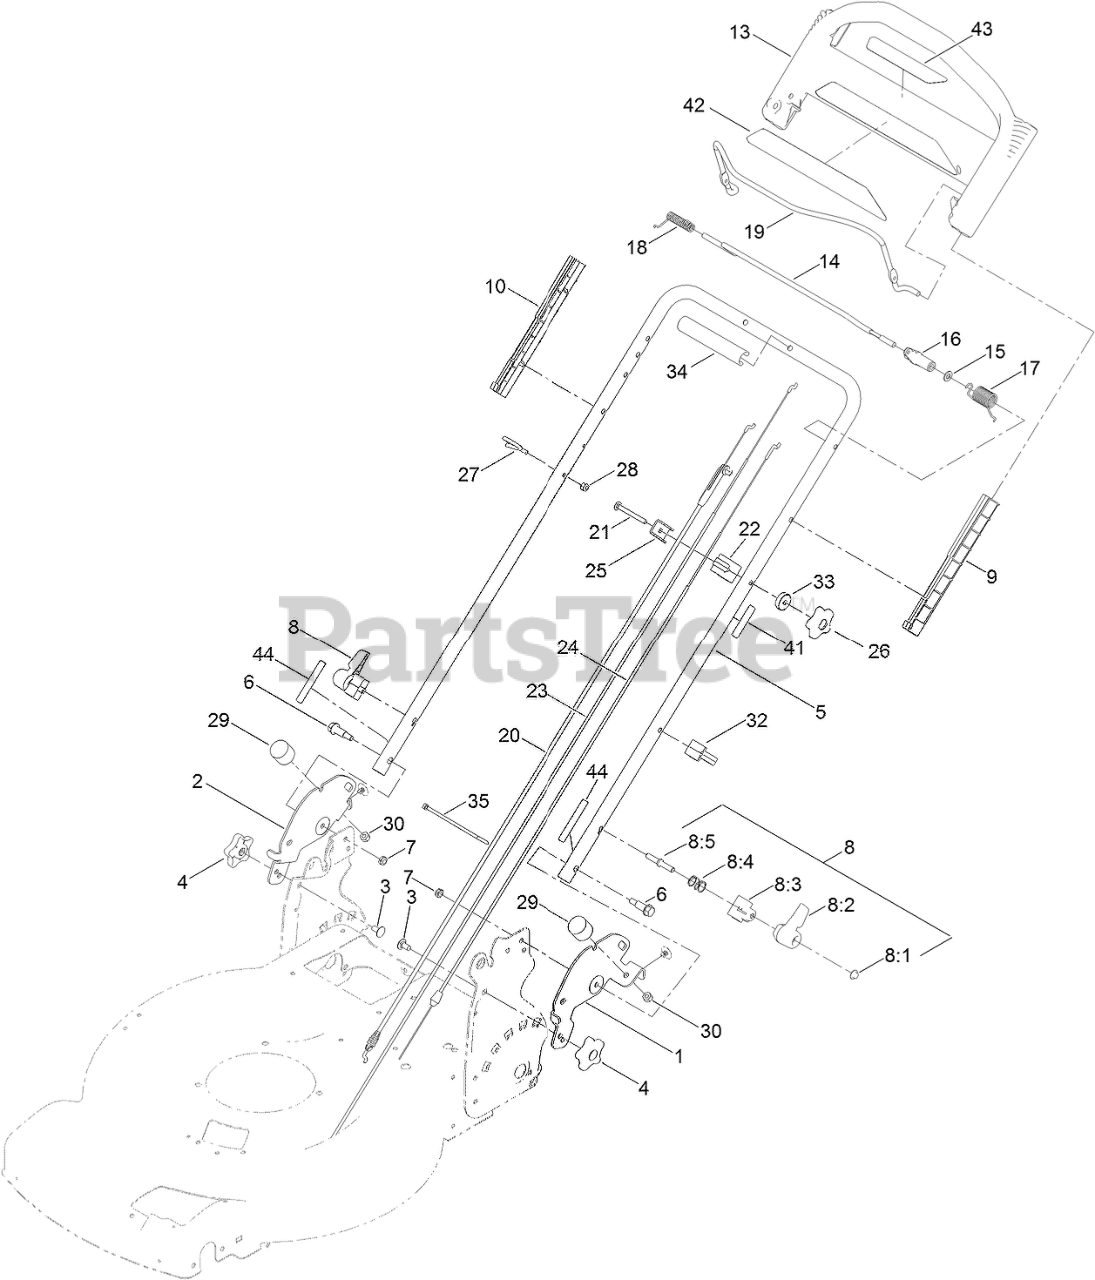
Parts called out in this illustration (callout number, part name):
1	BRKT-FLOAT, LH
2	BRKT-FLOAT, LH
3	SCREW-CARR
4	KNOB-HANDLE
6	BOLT-SHOULDER
7	NUT-LOCK, NI
8	QUICK RELEASE ASM
8:1	NUT-PUSH
8:2	LEVER
8:3	ANCHOR-SPRING
8:4	SPRING-COMPRESSION
8:5	ROD-RELEASE
9	GUIDE, LH
10	GUIDE, RH
13	HANDLE-PACE, PERSONAL
14	BAR-CONTROL, TRACTION
15	WASHER-PLAIN
16	LEVER-TRACTION
17	SPRING-TORSION
18	Spring-Torsion
19	BAIL-BRAKE
20	CABLE-BRAKE
21	SCREW-CARR
22	MOUNT-CABLE, TRACTION
23	CABLE-TRACTION, FRONT
24	CABLE-TRACTION, REAR
25	CLAMP-CABLE
26	KNOB-HANDLE, LOCKING
27	GUIDE-ROPE
28	NUT-LOCK, NI
29	BUMPER-RUBBER
30	NUT-LOCK, NI
32	GUIDE-CABLE
33	WASHER-CURVED
34	HANDLE-COVER
35	TIE-CABLE
41	DECAL-ADJUSTMENT
42	DECAL-POWEREVERSE
43	DECAL-DRIVE INSTRUCTION
44	DECAL-FLEXHEIGHT
